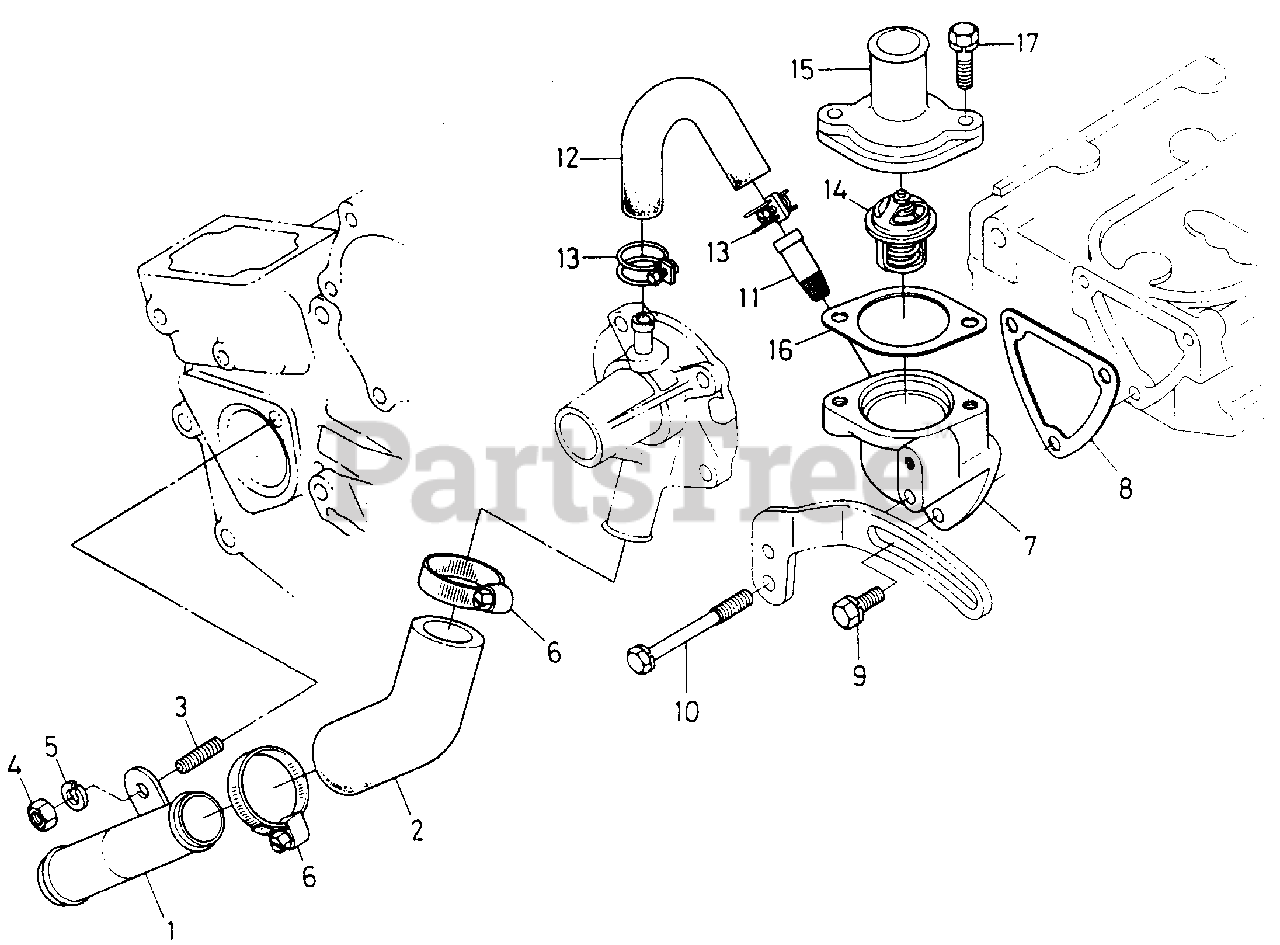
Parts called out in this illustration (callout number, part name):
1	Pipe, Water 2
2	Pipe, Water 3
4	Nut, M6 Znd Class 8
5	Washer, 6MM Lock
6	Clamp. No. 16 Type F Hose
7	Housing, Thermostat
8	Gasket
9	Bolt, M6 X 16 Class 8.8
11	Pipe, Water Return 1
12	Pipe, Water Return 2
13	Clamp, No. 10 Type F Hose
14	Thermostat
15	Cover, Thermostat
16	Gasket, Thermostat
